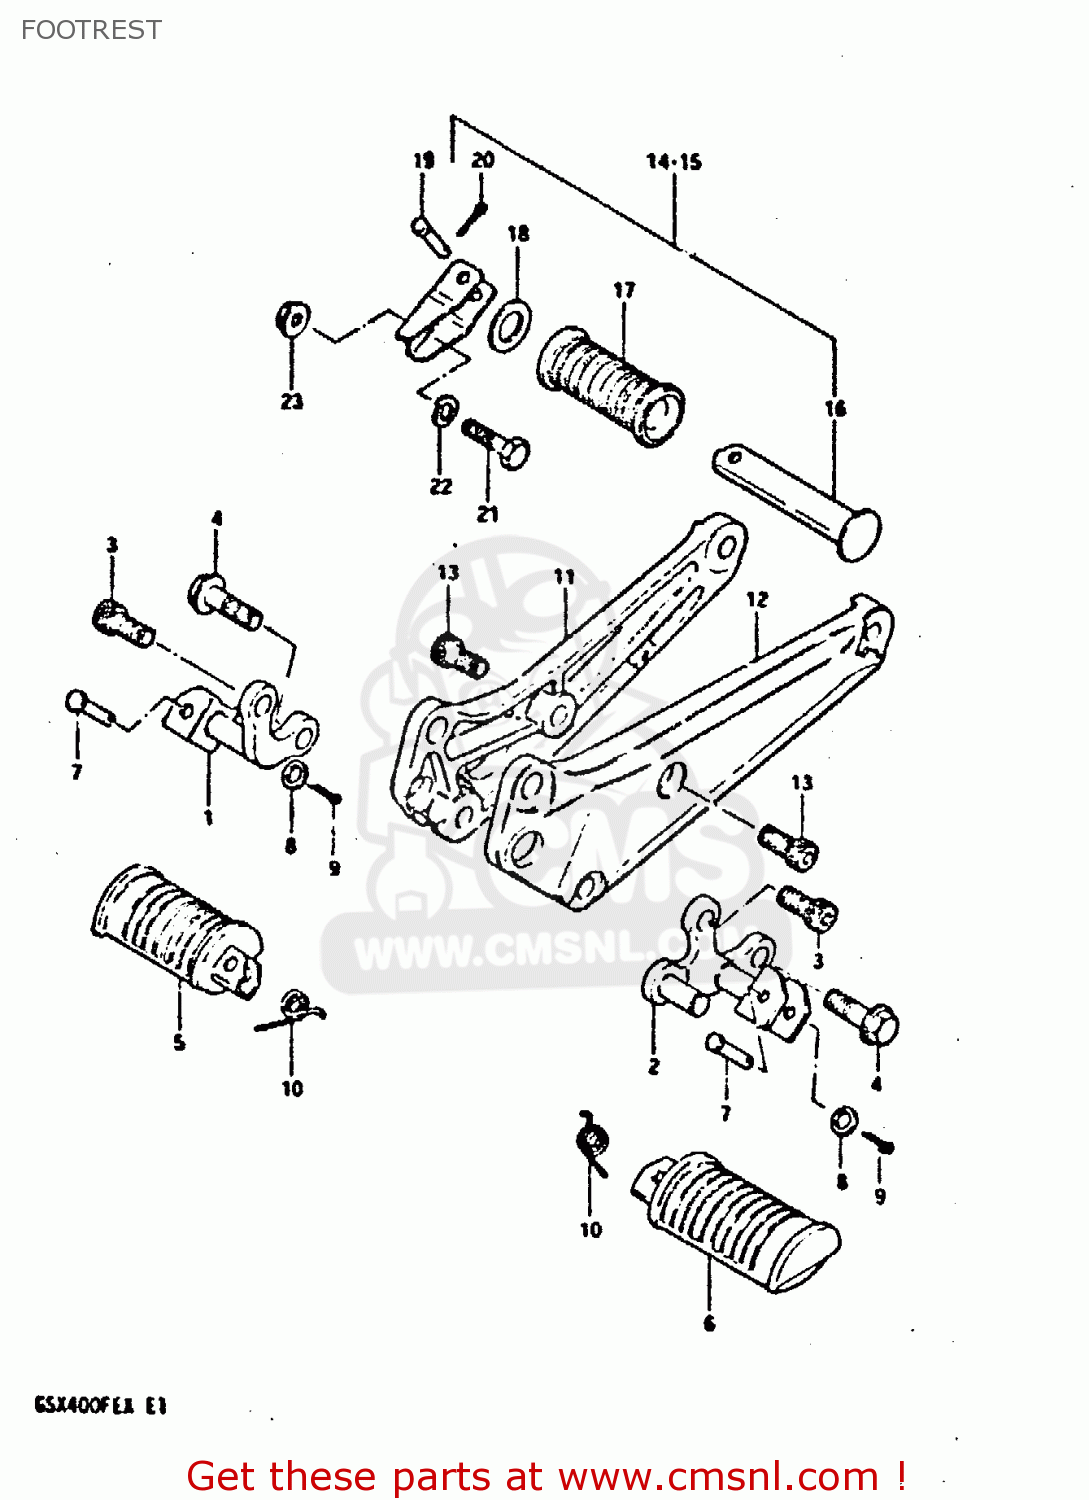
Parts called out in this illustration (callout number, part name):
1	BAR, FRONT FOOTREST RH
2	BAR, FRONT FOOTREST LH
3	BOLT
4	BOLT, LOWER
5	RUBBER,FR FOOT
6	RUBBER, LH
7	PIN
8	WASHER
9	PIN
10	SPRING
11	BRACKET, MUFFLER RH
12	BRACKET, MUFFLER LH
13	BOLT
14	FOOTREST, PILLION RH
15	FOOTREST, PILLION LH
16	BAR,FOOTREST RUBBER
17	RUBBER,PILLION FOOTREST
18	WASHER (19.5X32X2)
19	PIN
20	PIN
21	BOLT,M10X1.25X
22	LOCK WASHER
23	NUT
